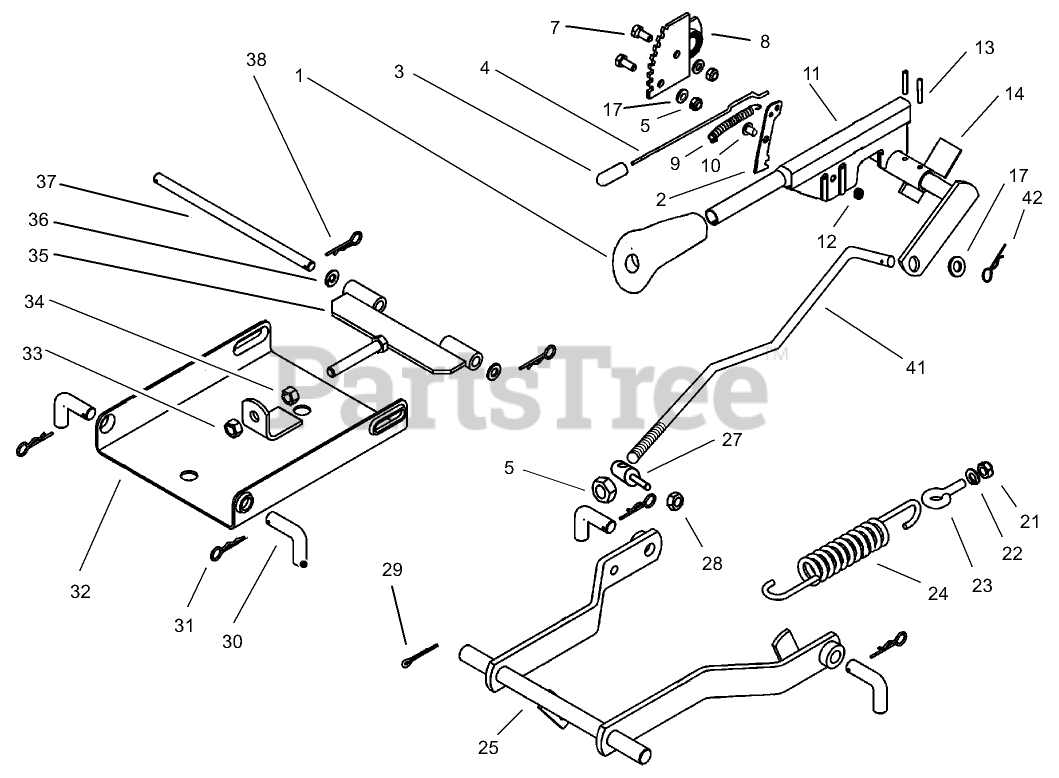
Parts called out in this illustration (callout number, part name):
1	GRIP-HANDLE
2	RATCHET-PLATE, PIVOT
3	BUTTON-PLUNGER
4	ROD-CONNECTION
5	NUT-LOCK, NI
7	SCREW-HH
8	SEGMENT-GEAR
9	SPRING
10	PIN-LEVER, ARM
11	LEVER-ARM, HEIGHT ADJ.
12	CLIP-PIN
13	PIN-SPRING
14	SHAFT-HEIGHT ADJ.
17	WASHER-PLAIN
21	NUT-LOCK, NI
22	WASHER-FLAT
23	BOLT-EYE
24	SPRING-LIFT
25	PIVOT ARM ASM
27	PIN-LIFTING
28	NUT-LOCK, NI
29	PIN-COTTER
30	PIN-BENT
31	PIN-HAIR
32	SUSPENSION-MOWER DECK, FRONT
33	NUT-HEX
34	NUT-HEX
35	HOLDER-FRONT
36	WASHER-FLAT
38	PIN-HAIR
41	ROD-HEIGHT, ADJ.
42	PIN-COTTER
